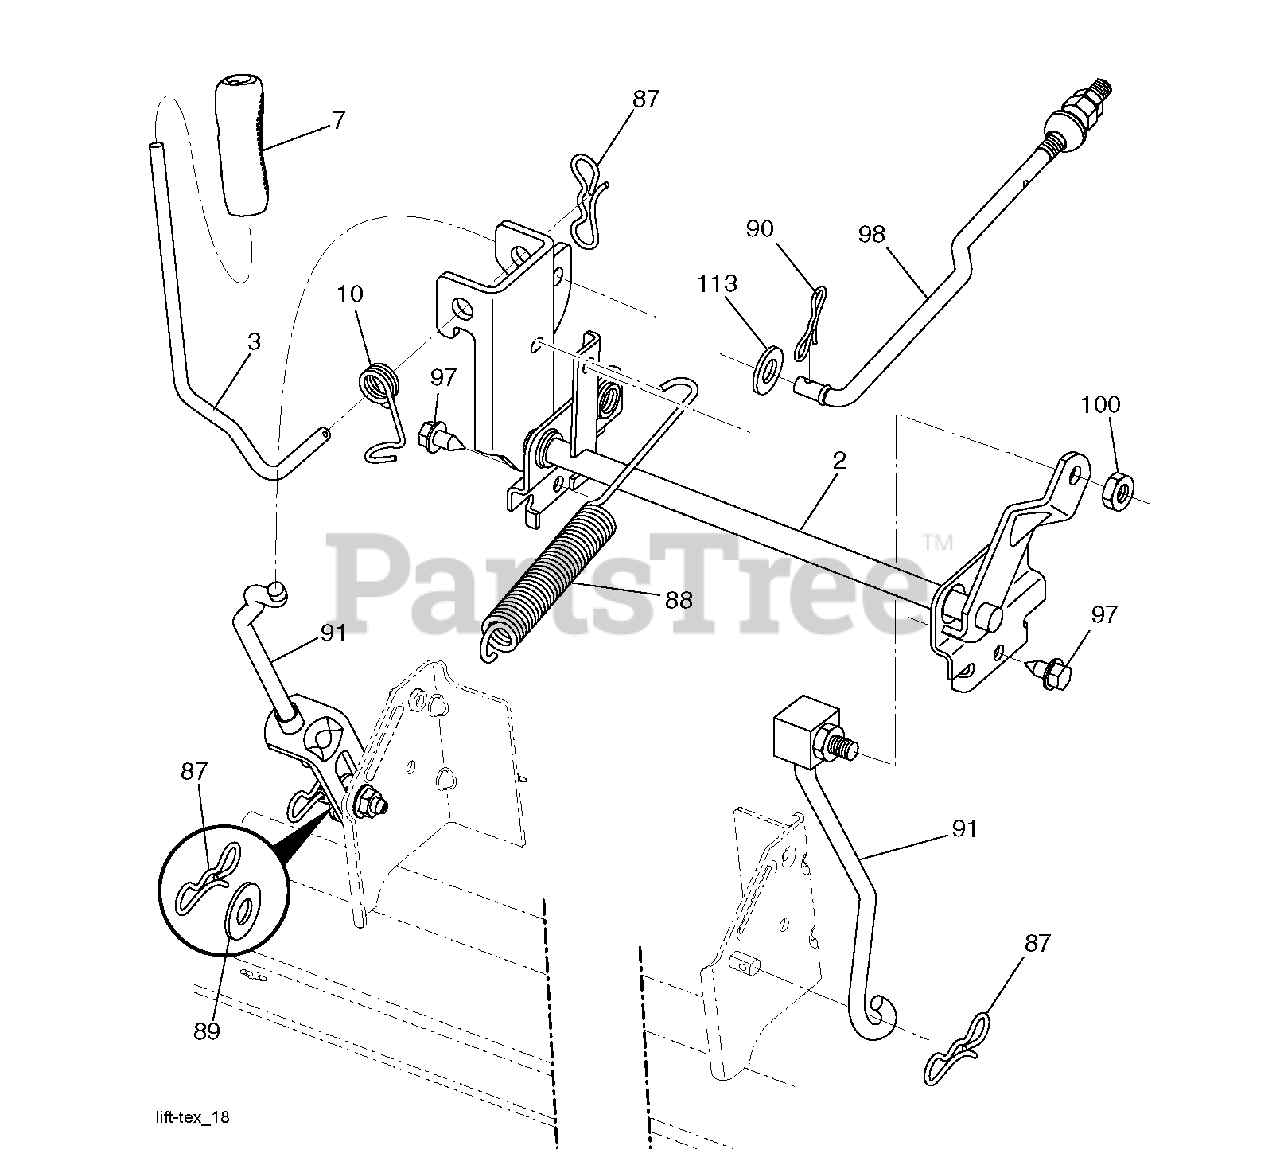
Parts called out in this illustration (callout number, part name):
2	SHAFT.ASM.LIFT.CROSS.H
3	LEVER.LIFT.HANDLE.LT
7	GRIP.HANDLE.LIFT.PVC.BLACK
10	SPRING.TORSION.LIFT.HANDLE
87	PIN.COTTER.7/16.BOW TI
88	SPRING.LIFT.ASSIST
89	WASHER.CLEAR.ZINC
90	PIN.COTTER.5/16.BOW TI
91	LINK.ASM.LIFT.REAR
97	SCREW, 3/8-16X3/4
98	LINK.ASM.SUSP.FRONT.MWR.10.5
100	LOCKNUT
